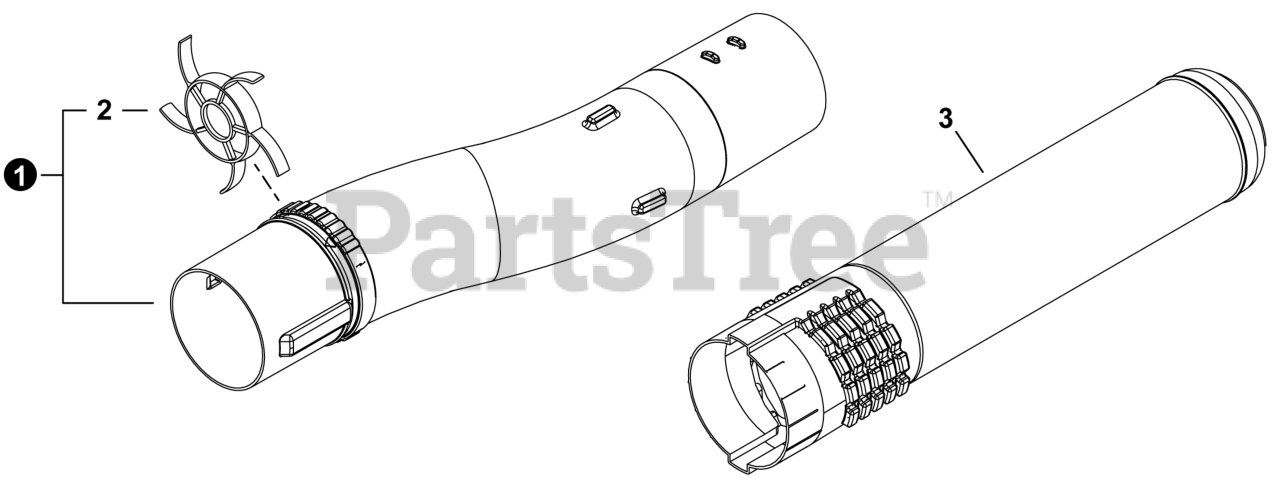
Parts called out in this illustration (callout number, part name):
1	TUBE, BLOWER - CURVED
2	GUARD - BLOWER TUBE
3	TUBE, BLOWER - NOZZLE
